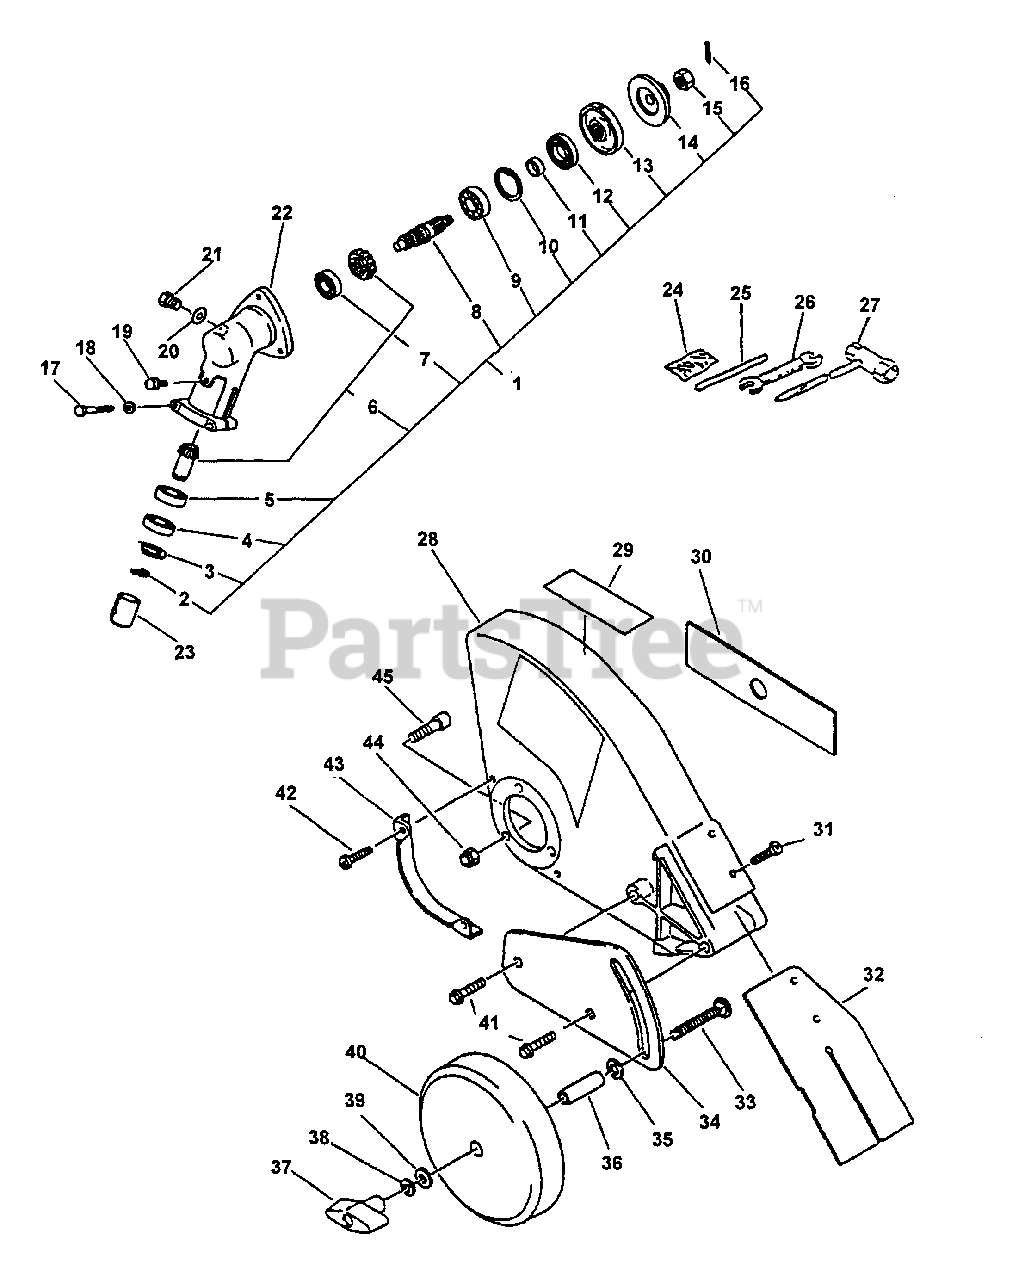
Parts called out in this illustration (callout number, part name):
1	GEAR CASE ASSY
2	RING, RETAINING - 18
3	RING, RETAINING
4	BEARING, BALL - 609
5	BEARING, BALL - 609
6	GEAR SET
7	BEARING, BALL - 629
8	GEAR - SHAFT
9	BEARING, BALL - 6201
10	RING, RETAINING - 20
12	SEAL, OIL
13	ADAPTOR, BLADE - UPPER
14	ADAPTOR, BLADE - LOWER
15	NUT - 10 -- LEFT HAND
16	PIN, SPLIT - 2X22
17	BOLT - 5X30
18	WASHER - 5
19	SCREW - 5X12
21	FITTING, GREASE
22	CASE, GEAR
23	COLLAR
24	PIN, SPLIT - 2X22
25	LOCKING TOOL
26	SPANNER - 8X10mm
27	T-WRENCH - 17X19mm
28	SHIELD, DEBRIS
29	LABEL - CAUTION
30	BLADE, EDGER
31	SCREW - 3
32	FLAP, DEBRIS
33	BOLT - CARRIAGE
34	BRACKET, WHEEL
35	WASHER - 10
36	COLLAR - 12
37	WINGNUT - 5/16-18
38	LOCKWASHER - 8
39	WASHER - 8
40	WHEEL - 6X1.5
41	BOLT - 8X14
42	SCREW - 4X16
44	LOCKNUT - 5
45	SCREW - 5X22
